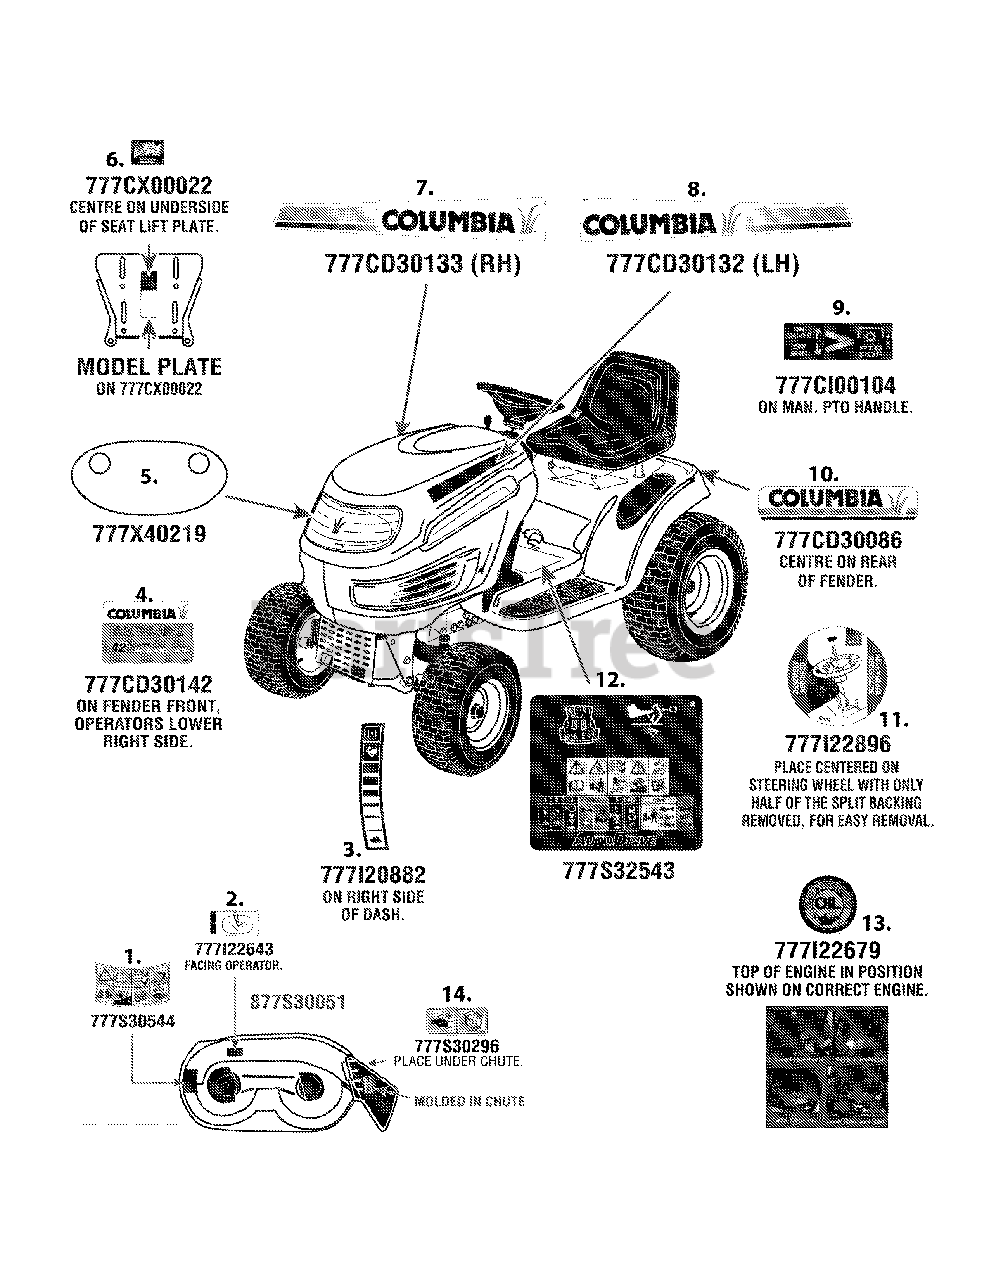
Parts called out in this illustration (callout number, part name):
1	LABEL-DECK SAFETY
2	LABEL-DECK BELT ROUTE 42"
3	LABEL-DASH THROTTL
4	LABEL-CVT 42" FNDR
5	LABEL-LENS REFLECT
6	LABEL-MADE IN USA
7	LABEL-HOODSIDE RH STY 6
8	LABEL-HOODSIDE LH STY 6
9	LABEL-MANUAL PTO CANADA
10	LABEL-REAR FENDER
11	LABEL:RIDER STEERING WHEEL CAP
12	LABEL-SAFETY
13	LABEL-CHECK ENG OIL
14	LABEL:RIDER DECK: UNDERCHUTE EXP
